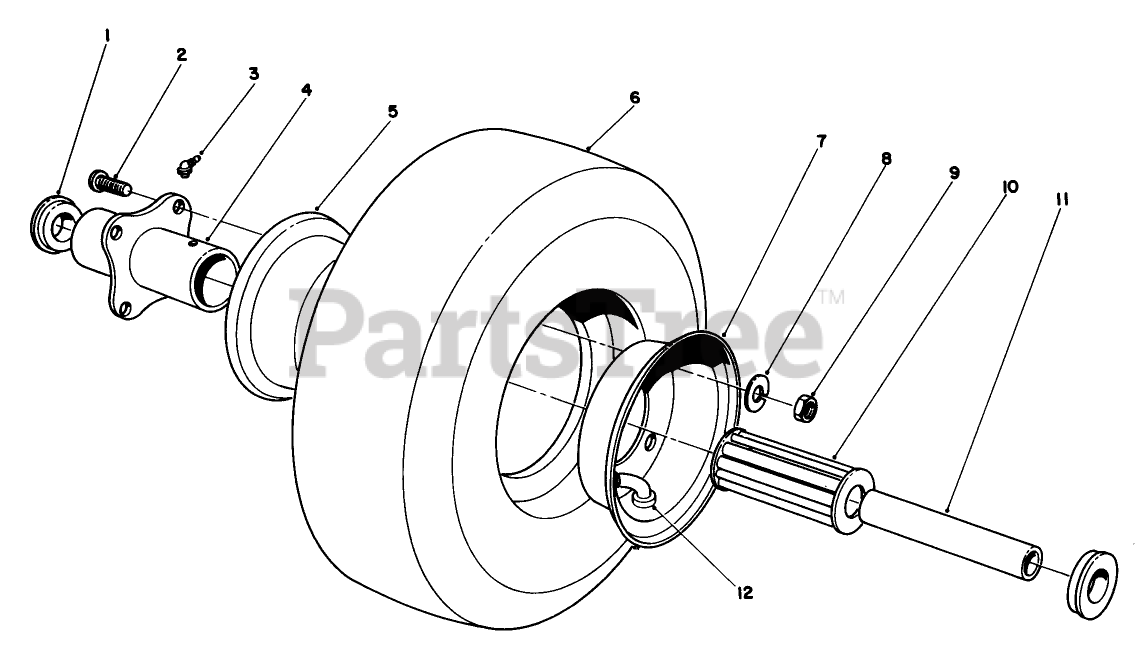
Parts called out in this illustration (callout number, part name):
1	RETAINER
2	WHEEL BOLT
3	FITTING-GREASE
4	HUB-CENTERED
5	WHEEL HALF-FEMALE
6	TIRE-10 INCH (2-PLY)
7	WHEEL HALF-MALE
8	WASHER-LOCK
9	NUT-HEX
10	ROLLER BEARING
11	SPANNER-BUSHING
